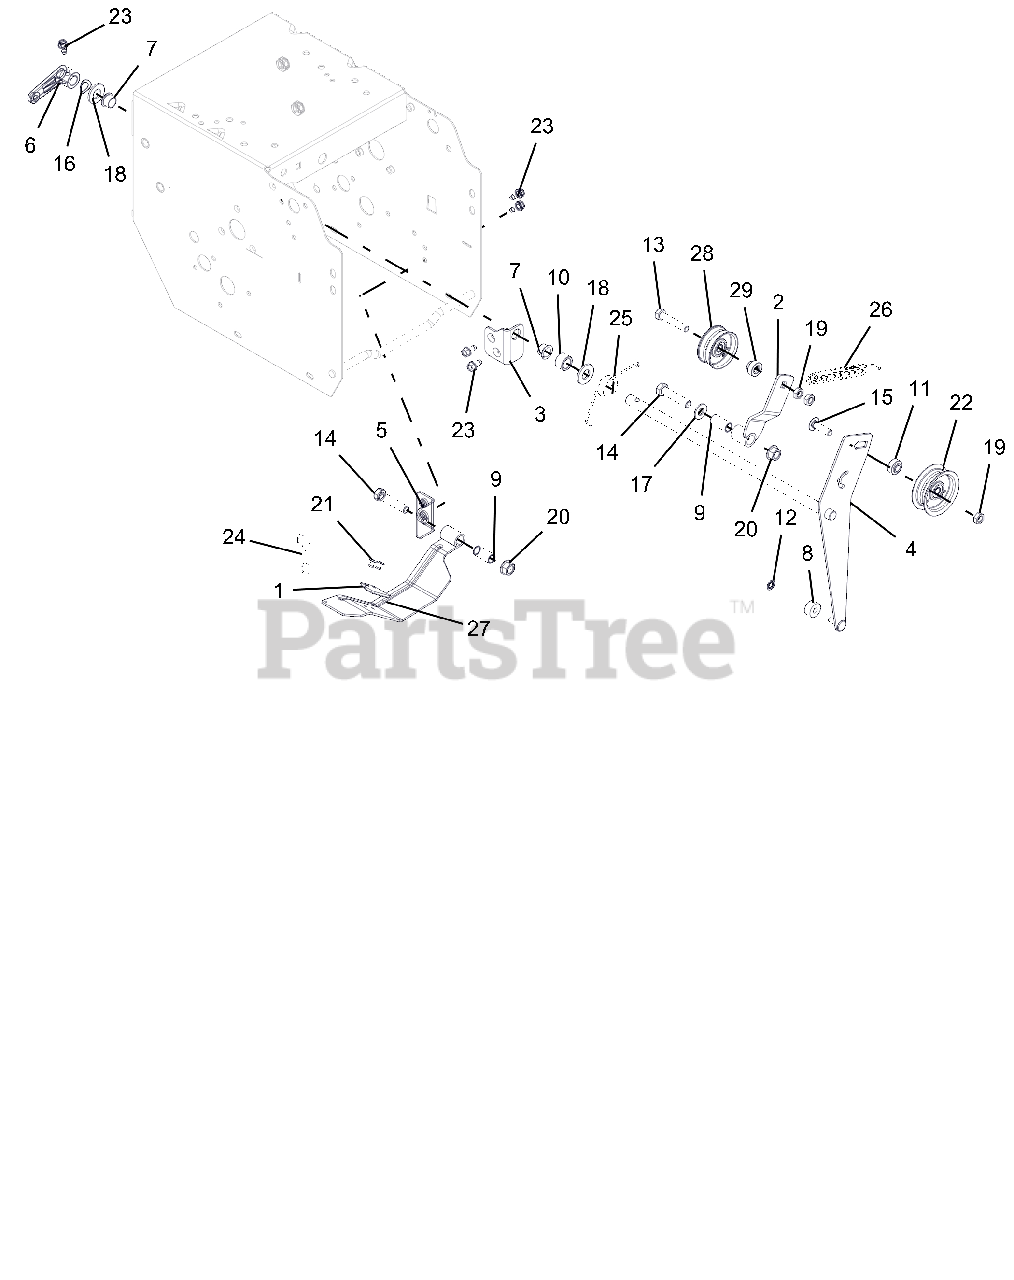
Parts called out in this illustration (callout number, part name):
1	PAD, BRAKE
2	ARM, TRACTION IDLER
3	BRACKET, MOUNT - IDLER ARM
4	WELDMENT, ATTACHMENT IDLER ARM
5	BRACKET, MOUNT - BRAKE
6	ARM, CLUTCH - ATTACHMENT
7	BUSHING, POLYLINER-.50 SPLIT
8	BSHG,SLV .265 X .625 X .375
9	BSHG-SLV .385X.500X1.045
10	BSHG-SLV .510X.751X.475
11	SPCR, BRG .315X.500X.358X.281
12	RG-RTNG-EXT .250X.010
13	@BLT-HEX .31-18X1.75 GR5 YWZC
14	@BLT-HEX .38-16X1.75 GR5 YWZC
15	BLT-RDHDSQSHNK.31-18X1.13 G5YZ
16	WSHR-WAVE .50X.75X.015 .13FRHT
17	@WSHR-FL-STL.406X.812X.065 YWZ
18	@WSHR-FL-STL.531X1.06X.095YWZC
19	@NUT-LK-CTR-JAM .31-18 YWZC
20	@NUT-LK-TOP-FLG .38-16 YWZC
21	RVT-POP .187 YZ
22	IDLER, FLAT - 2.00"
23	SCR-TAP .25-20X.50 HWH TR YWZ
24	SPRING-EXT .437 X .438 X 2.64
25	SG-TORS .075 X .955
26	SPRING, EXTENSION
27	BRAKE ARM W/PAD
28	IDLER, FLAT - 1.875"
29	SPCR, BRG .315X.500X.481X.281
